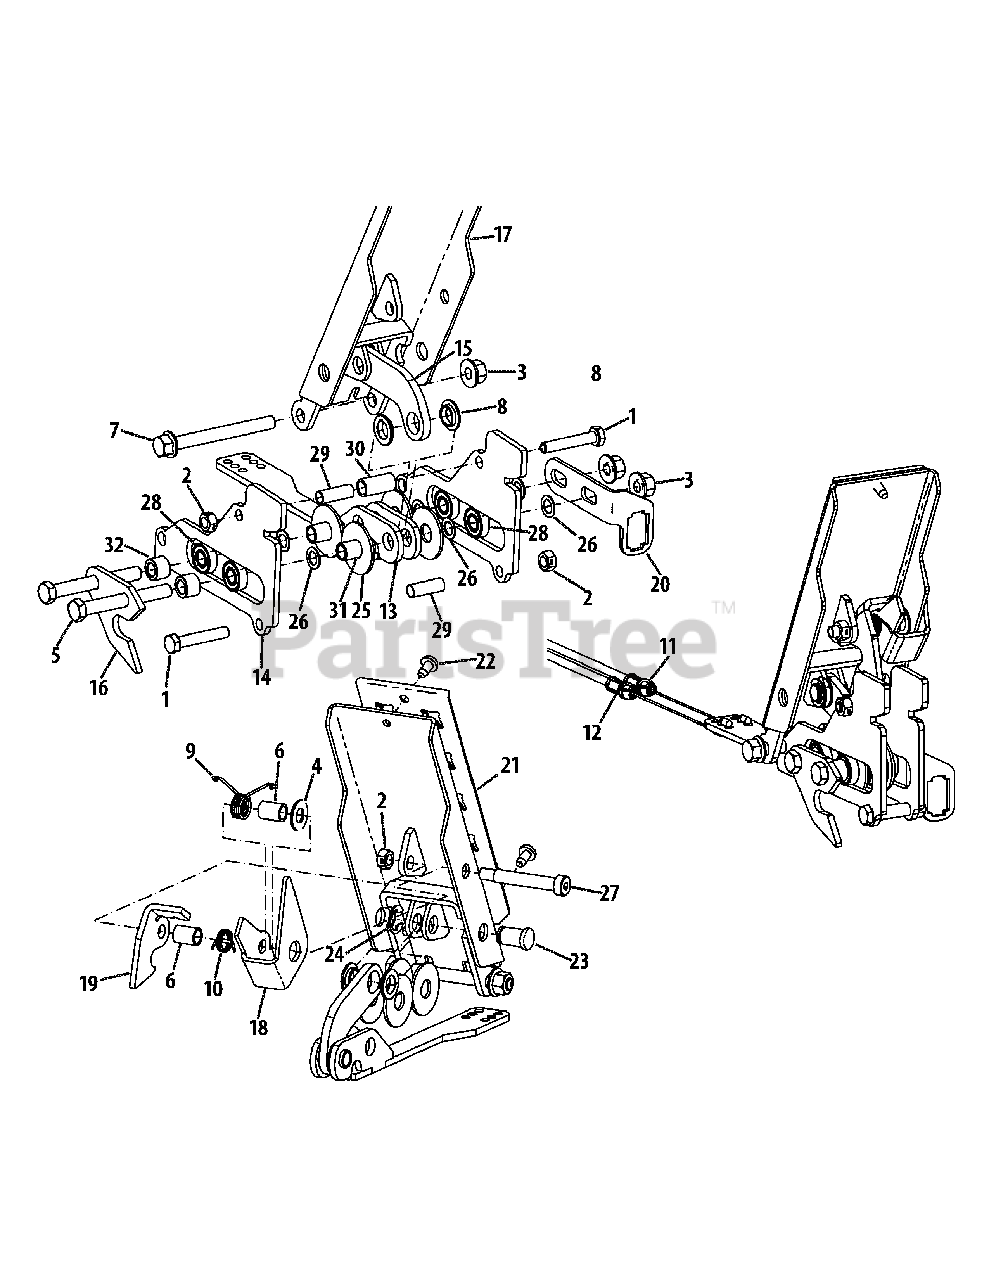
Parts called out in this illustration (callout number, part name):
1	Hex Screw, 5/16-18 x 1.75
2	Counter Lock Nut, 5/16-18
3	Flange Counter Lock Nut, 3/8-16
4	Washer, .416 x .875 x .046
5	Hex Screw, 3/8-16 x 3.00
6	Spacer, .380 x .500 x .667
7	Hex Screw, 3/8-16 x 3.50
8	Flange Bearing, .502 x .875 x .180
9	Torsion Spring
10	Torsion Spring
11	LH Brake Cable
12	RH Brake Cable
13	Brake Carrier Assembly
14	Brake Roller Guide Bracket
15	Brake Control Link
16	Lockout Plate
17	Brake Pedal Assembly
18	Park Engagement Bracket
19	Brake Hook Bracket
20	Brake Switch Mount Bracket
21	Brake Pedal Grip
22	Screw, 1/4-20 x .5
23	Pin, .500 x .804
25	Flat Washer, .531 x 1.5 x .08
26	Washer, .39 x .62 x .03
27	Shoulder Screw, 5/16-18 x .375 x 2.00
28	Bearing, .375 x .875
29	Spacer, .319 x .375 x 1.056
30	Spacer, .384 x .500 x 1.000
31	Spacer, .38 x .5 x .955
32	Spacer, .385 x .625 x .458
